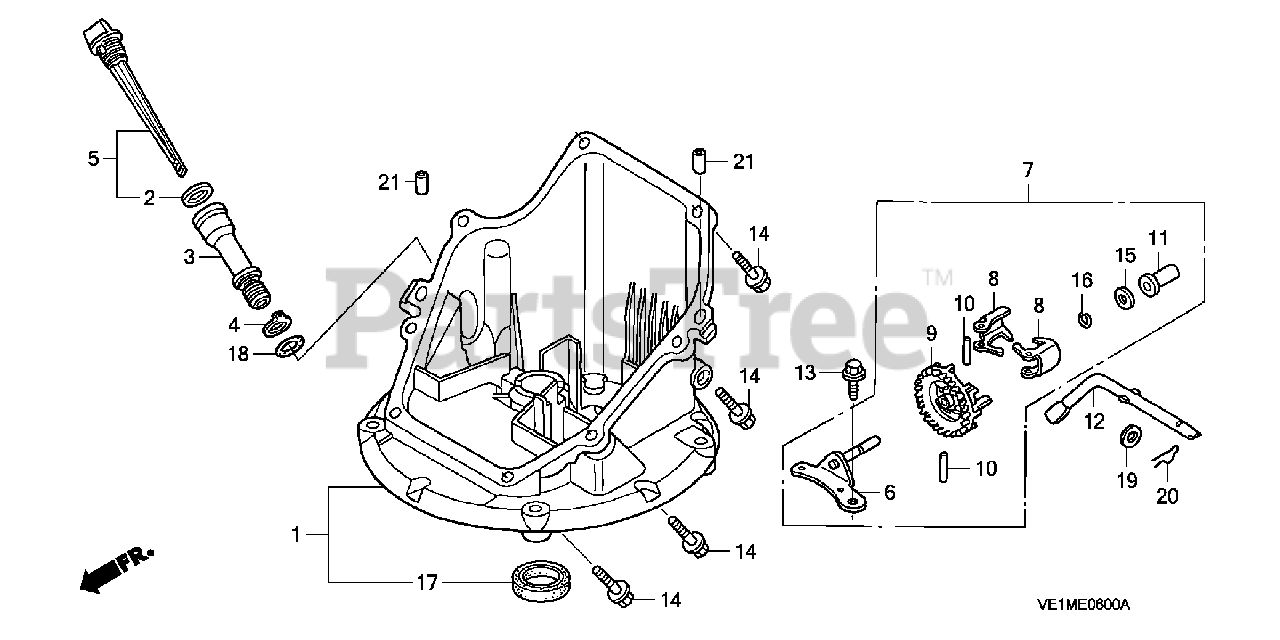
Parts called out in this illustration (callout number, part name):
1	PAN ASSY., OIL
2	GASKET, OIL FILLER CAP
3	EXTENSION, OIL FILLER
4	WASHER, EXTENSION LOCK
5	GAUGE ASSY., OIL LEVEL
6	SHAFT, GOVERNOR HOLDER
7	GOVERNOR ASSY.
8	WEIGHT, GOVERNOR
9	HOLDER, GOVERNOR WEIGHT
10	PIN, GOVERNOR WEIGHT
11	SLIDER, GOVERNOR
12	SHAFT, GOVERNOR ARM
13	BOLT, FLANGE (6X14) (CT200)
14	BOLT, FLANGE (6X25) (CT200)
15	WASHER, THRUST (6MM)
16	CLIP, GOVERNOR HOLDER
17	OIL SEAL (28X41.25X6)
18	O-RING (14.8X2.4) (NOK)
19	WASHER, PLAIN (6MM)
20	PIN, LOCK (8MM)
21	PIN, DOWEL (8X20)
